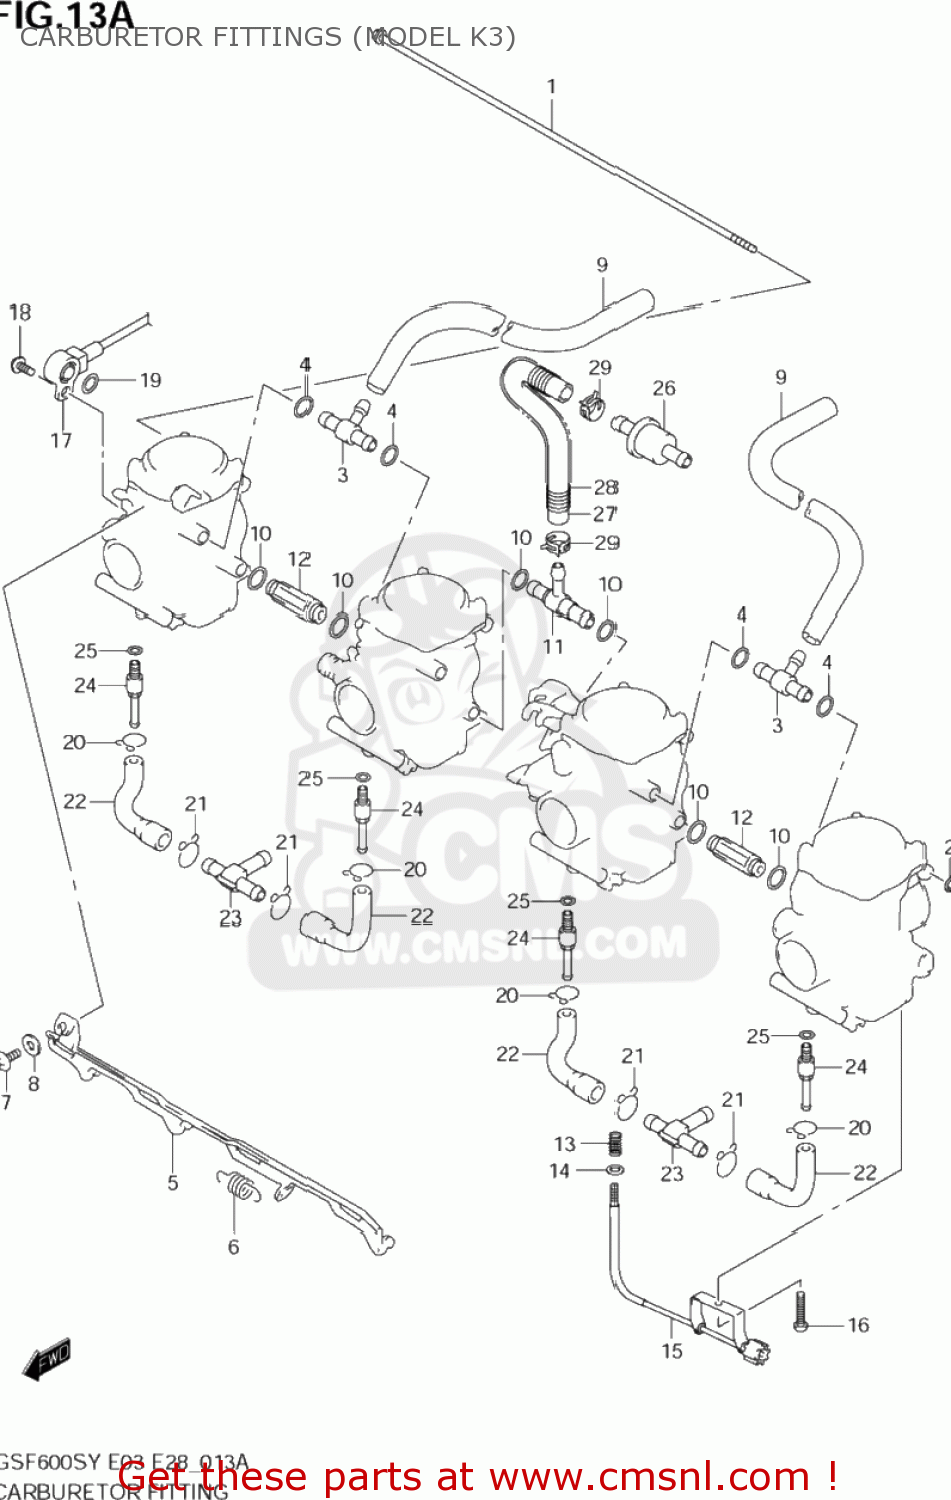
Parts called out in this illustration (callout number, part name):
1	BOLT
2	NUT
3	JOINT
4	O RING
5	LEVER,STARTER
6	SPRING
7	SCREW
8	WASHER
9	HOSE(7X11X600)
10	O RING
11	JOINT
12	JOINT
13	SPRING
14	WASHER
15	ADJUSTER
16	SCREW
17	SENSOR ASSY,THROTTLE
18	SCREW
19	O RING
20	CLIP
21	CLIP
22	HOSE
23	JOINT
24	JOINT
25	O RING
26	STRAINER COMP,FUEL
27	HOSE,FUEL
28	SPRING
29	CLIP
